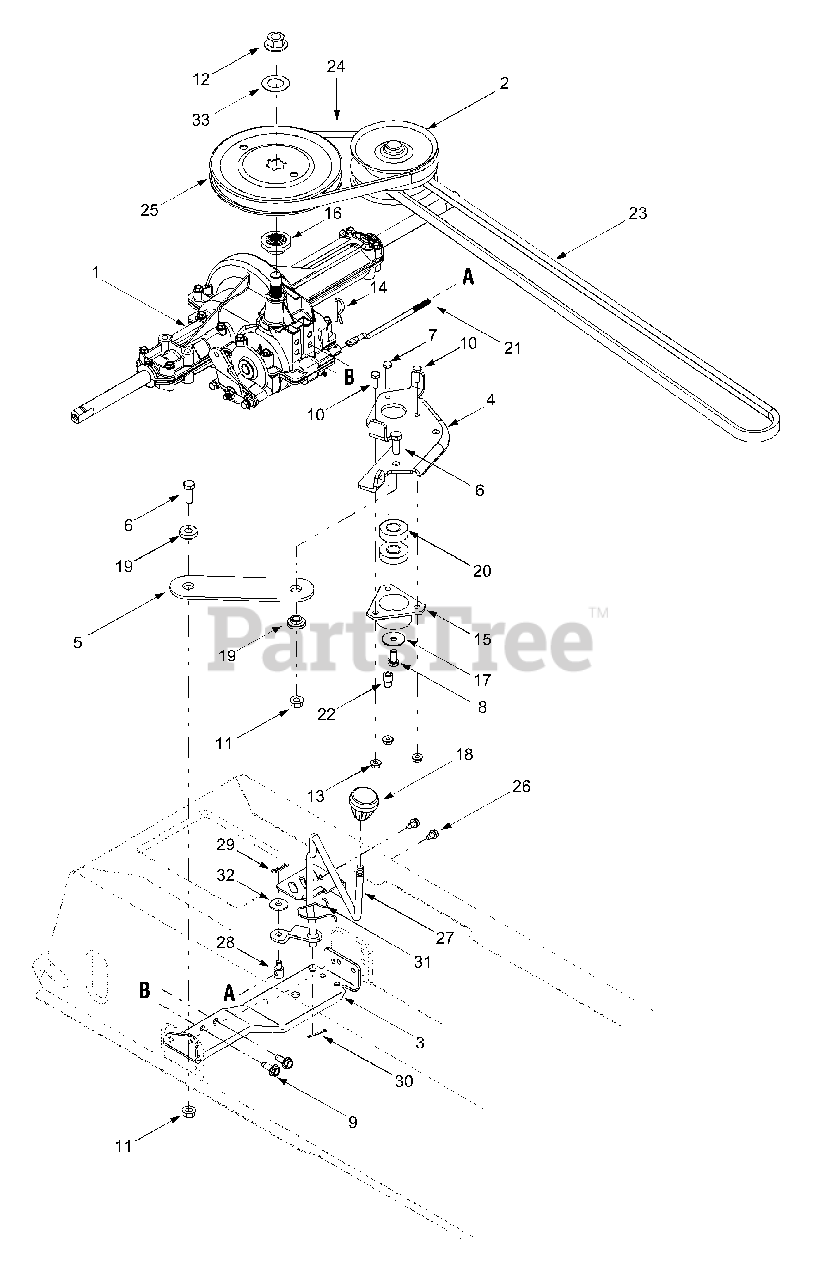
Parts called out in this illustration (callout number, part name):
1	Transmission, Single-speed
2	Variable-speed Pulley, 4.75
3	Torque Bracket
4	Variable-speed Bracket
5	Variable-speed Bracket
6	Hex Cap Screw, 3/8-16 x 1.0
7	Hex Cap Screw, 1/4-20 x 1.5
8	Hex Cap Screw, 5/16-24 x .75
9	Screw, 5/16-18 x .75
10	Hex Screw,1/4-20 x .75
11	Flange Lock Nut, 3/8-16
12	Flange Nut, 9/16-18
13	Flange Lock Nut, 1/4-20
14	Internal Cotter Pin, .125
16	Pulley Hub, 5/8 Spline
17	Flat Washer, .320 x 1.25 x .06
18	Shift Knob, 1.60 OD X 1.56
19	Shoulder Spacer, 1.0 x .38 x .38
20	Ball Bearing, 17 x 40 x 12
22	Stepped Spacer
23	Lower Drive Belt
24	Upper Drive Belt
25	Transmission Pulley, 7.25
26	Self-tapping Screw, 1/4-20 x .5
27	Shift Lever Assembly
28	Ferrule, 1/4-20 x 1.0
29	Cotter Pin, 1.13
30	Cotter Pin, 1.0
31	Spring Compression Clip
32	Flat Washer, 5/16 x .934 x .100
33	Flat Washer, .88 ID x 1.5 OD
